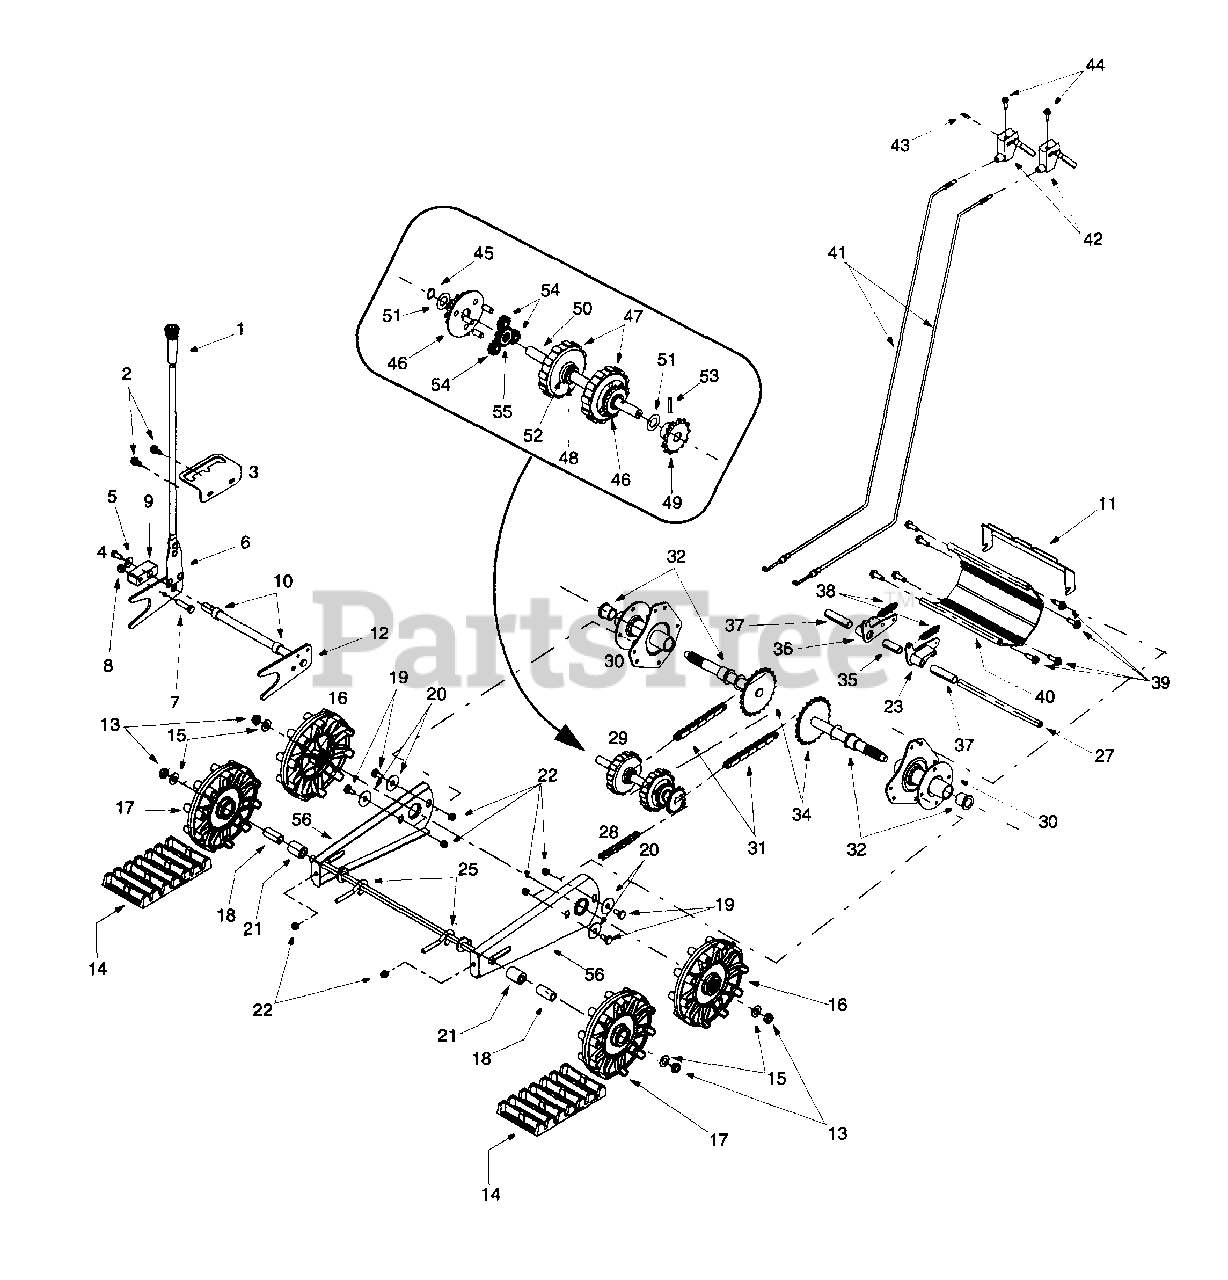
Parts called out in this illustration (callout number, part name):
2	Tap Screw, 5/16-18 x .625
4	Hex Cap Screw, 5/16-24 x .75
5	Bell Washer, .34 ID x .872 OD
7	Hex Cap Screw, 3/8-24 x 1.5
8	Hex Nut, 3/8-24
9	Lift Shaft Drive
10	Spacer, .628 ID x .875 OD x .5
13	Jam Nut, 1/2-20
15	Flat Washer, .5 x 1 x .06
16	Track Drive Wheel
17	Track Idler Wheel
18	Spacer, .51 ID x .75 OD x 1.67
19	Shoulder Screw, .435 x .178-5/16 x .56
20	Flat Washer, .442 x 1.38 x .06
21	Spacer, .51 ID x 1 OD x 1.34
22	Hex Nut, 5/16-18
23	LH Dogg Assembly
25	Eye Bolt, 5/16-18 x 3
27	Actuator Shaft
29	Track/Steering Shaft Assembly
32	Flange Bearing
34	Axle Assembly
35	Split Spacer, .514 x .630 x 1.59
36	RH Dogg Assembly
37	Split Spacer, .514 x .630 x 2.44
38	Ext. Spring
39	Tap Screw, 5/16-18 x 1
40	Track Housing
41	Steering Cable
42	Steering Trigger
44	Screw, #10-24 x 1.375
45	Retaining Ring
46	Carrier Assembly
47	Ring Gear
48	Retaining Ring
49	13-Tooth Sprocket
50	Track Steering Drive Shaft
51	Flat Washer, .58 x 1.06 x .02
52	Flat Washer, 5/8 x 1 x .03
53	Spirol Pin, 3/16 x 1
54	12-Tooth Gear
55	18-Tooth Gear
56	Track Side Plate
